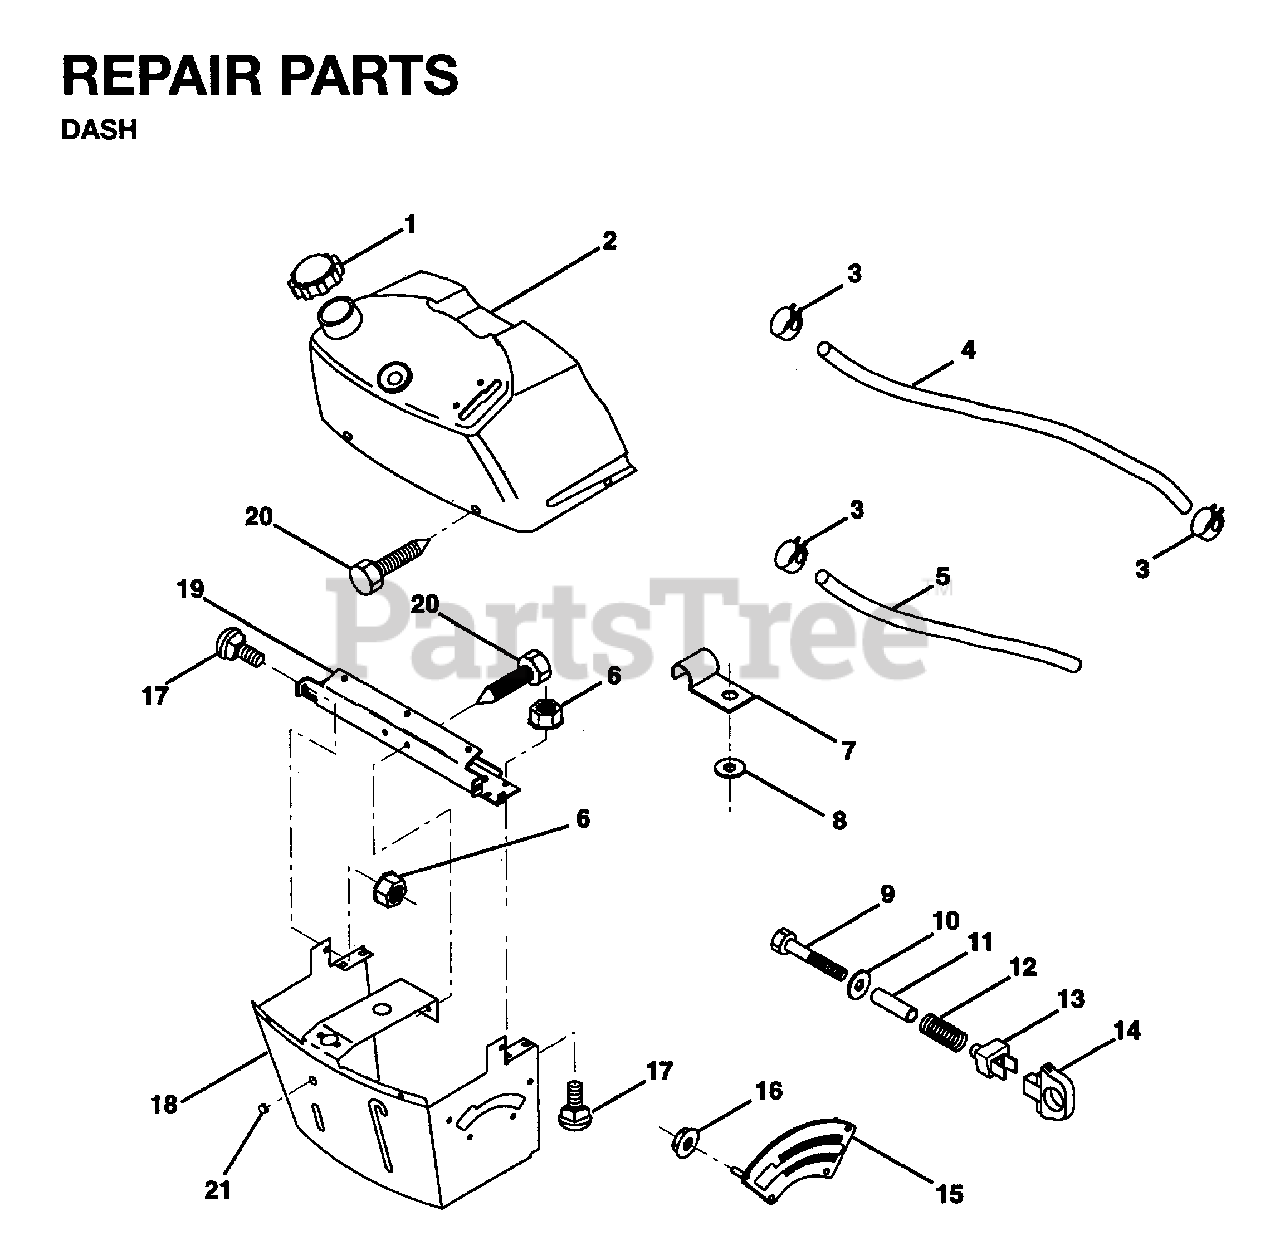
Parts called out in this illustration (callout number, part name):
3	HOSE CLAMP
4	FUEL LINE
5	FUEL LINE T
6	NUT.CROWNLOCK.1/4
7	CLIP T
8	WASHER PM
9	BOLT HEX FIN 1/4-20X1 3/4
11	SPACER SPLIT
12	SPRING.COMPRESSION
13	KNOB HGT RETAINER
14	KNOB
15	ADJUSTER QUAD
18	SUPT ASSY DASH
19	CROSS BRACE
21	PLUG DOME
